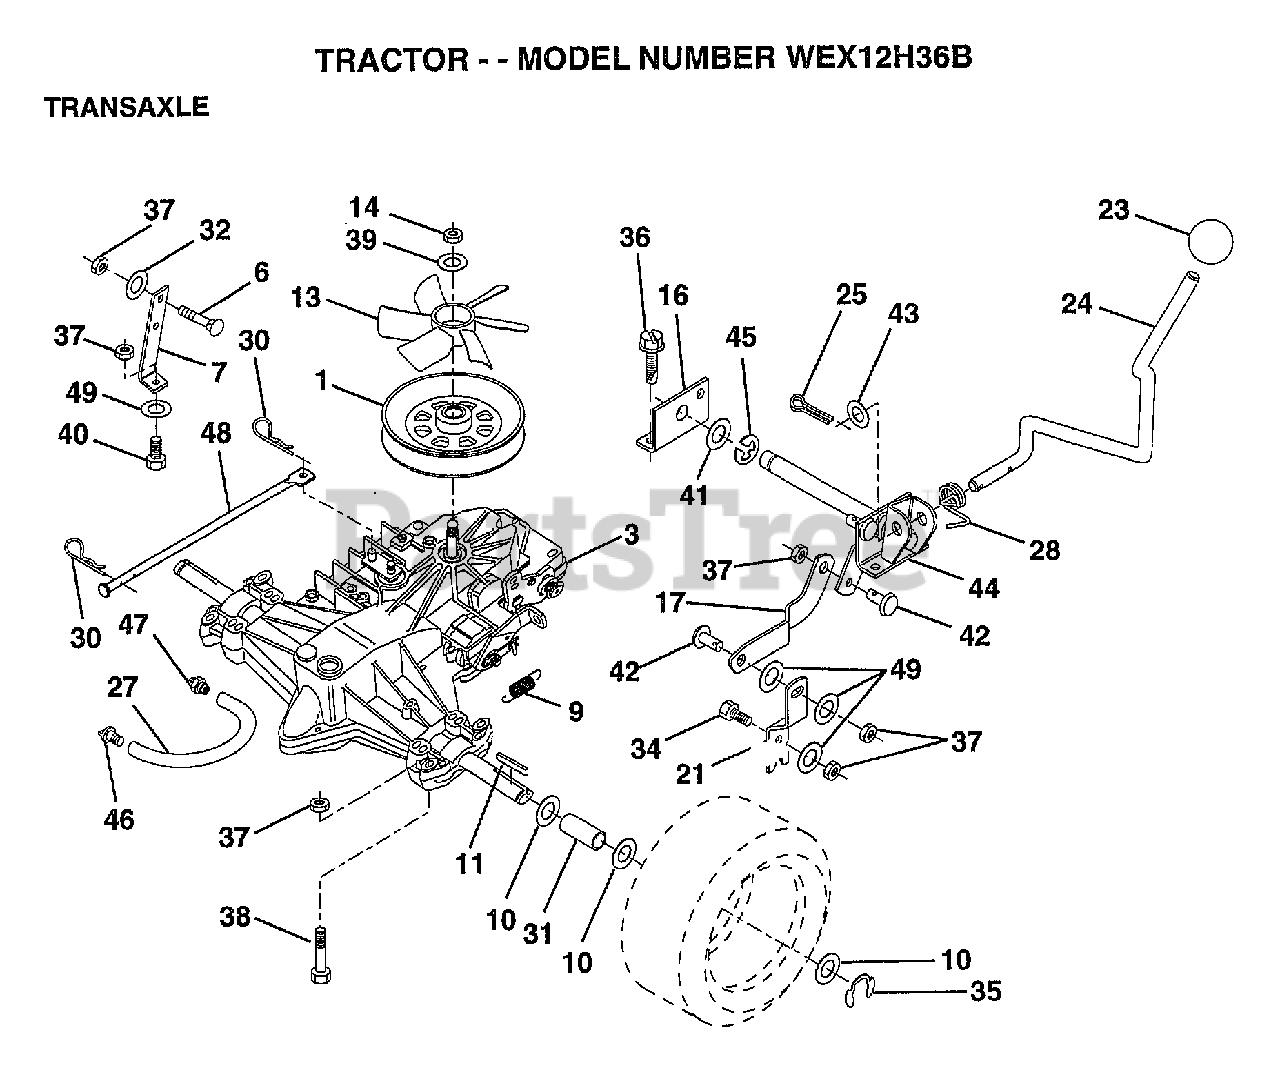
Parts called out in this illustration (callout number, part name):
1	PULLEY.V-GROOVE
3	TRANSAXLE HYD 0319-0500
6	BOLT
7	STRAP.TORQUE.HYD
9	SPRING.BRAKE.RETU
10	WASHER
11	SQUARE KEY
13	FAN.HYDRO.6FANS
14	"LOCKNUT,1/2-20UNF"
16	SUPPORT.HDLE.SHFT
17	LINK.SHIFT.HYD.LR
21	LEVER.SHIFT.TRANS
23	KNOB T (1/2-HOLE)
24	ROD.SHIFTER.HYD.
25	PIN COTTER 1/8
27	"LINE FUEL HYD 4"""
28	SPRING.TORSION.LR
30	RETAINER M
31	SPACER SPLIT
32	WASHER
35	E-RING LT
36	SCREW
37	NUT
38	BOLT.HEX.FLGHD
39	WASHER
40	BOLT.HEX.5/16-1.5
41	WASHER
42	PIN.PIVOT.SHIFT.
43	WASHER
44	SHAFT.PIVOT.LR.
48	ACTUATOR.BYPASS
49	WASHER M
